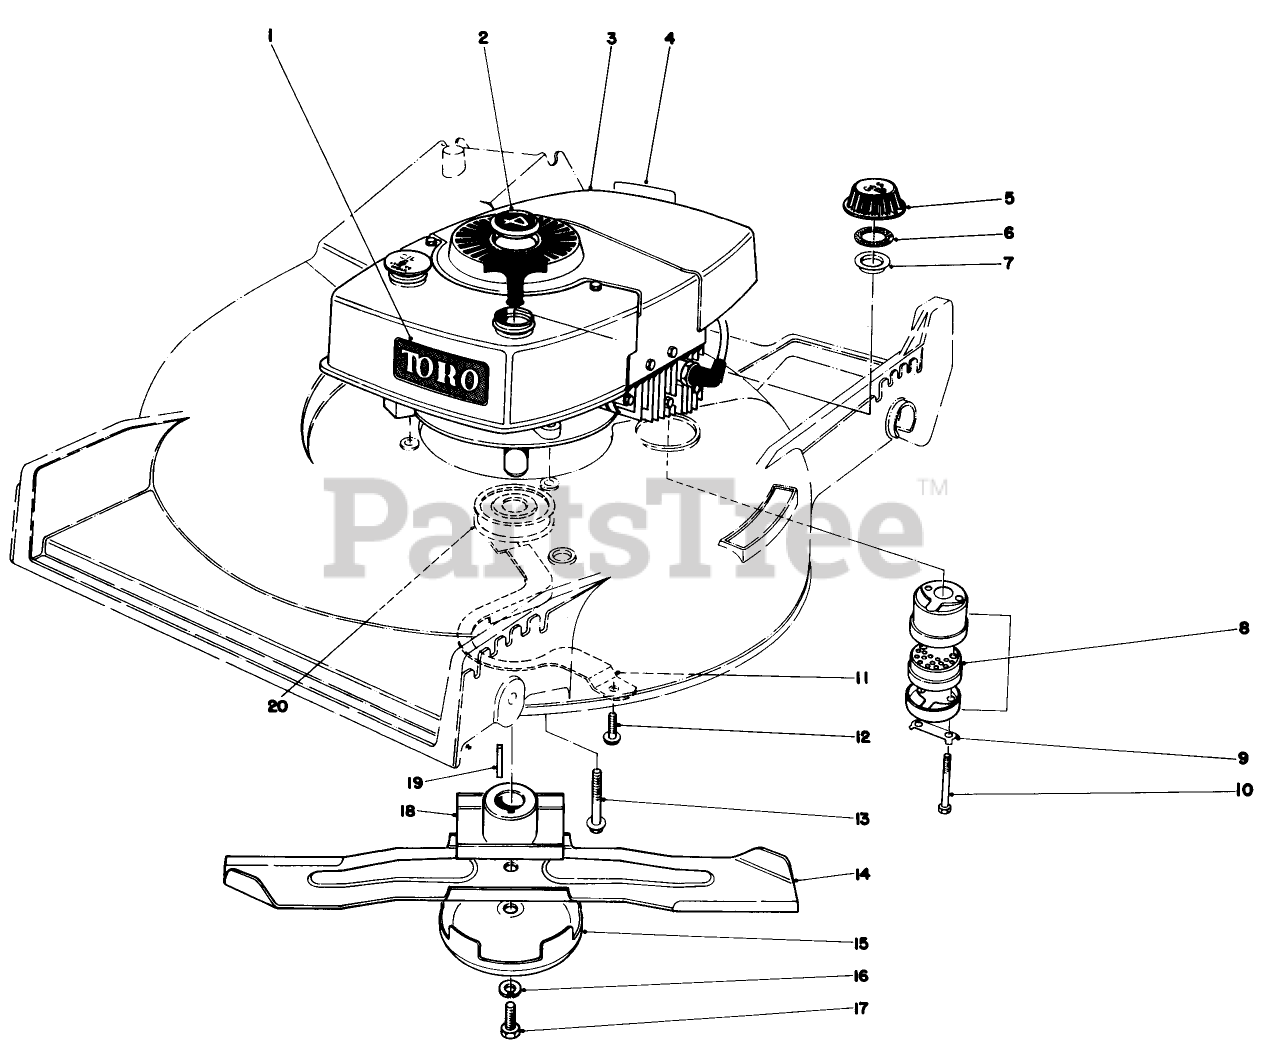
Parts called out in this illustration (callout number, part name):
1	Decal Tow
2	PLUG BUTTON
3	Engine
4	Decal-Maintenan
5	Gas Cap (Incl. Ref. #6 & 7)
6	GASKET
7	GAS CAP BAFFLE
8	Muffler Assy. (Incl. Ref. #9 &10)
9	CLIP - LOCKING
10	SCREW-HH
11	BELT GUIDE
12	Screw
13	SCREW-HWHTF
14	Blade
15	AntiScalp Cup
16	WASHER-LOCK
17	BLADE SCREW
18	BLADE RETAINER WA(BLACK)
19	KEY-SQUARE
20	DRIVER PULLEY
